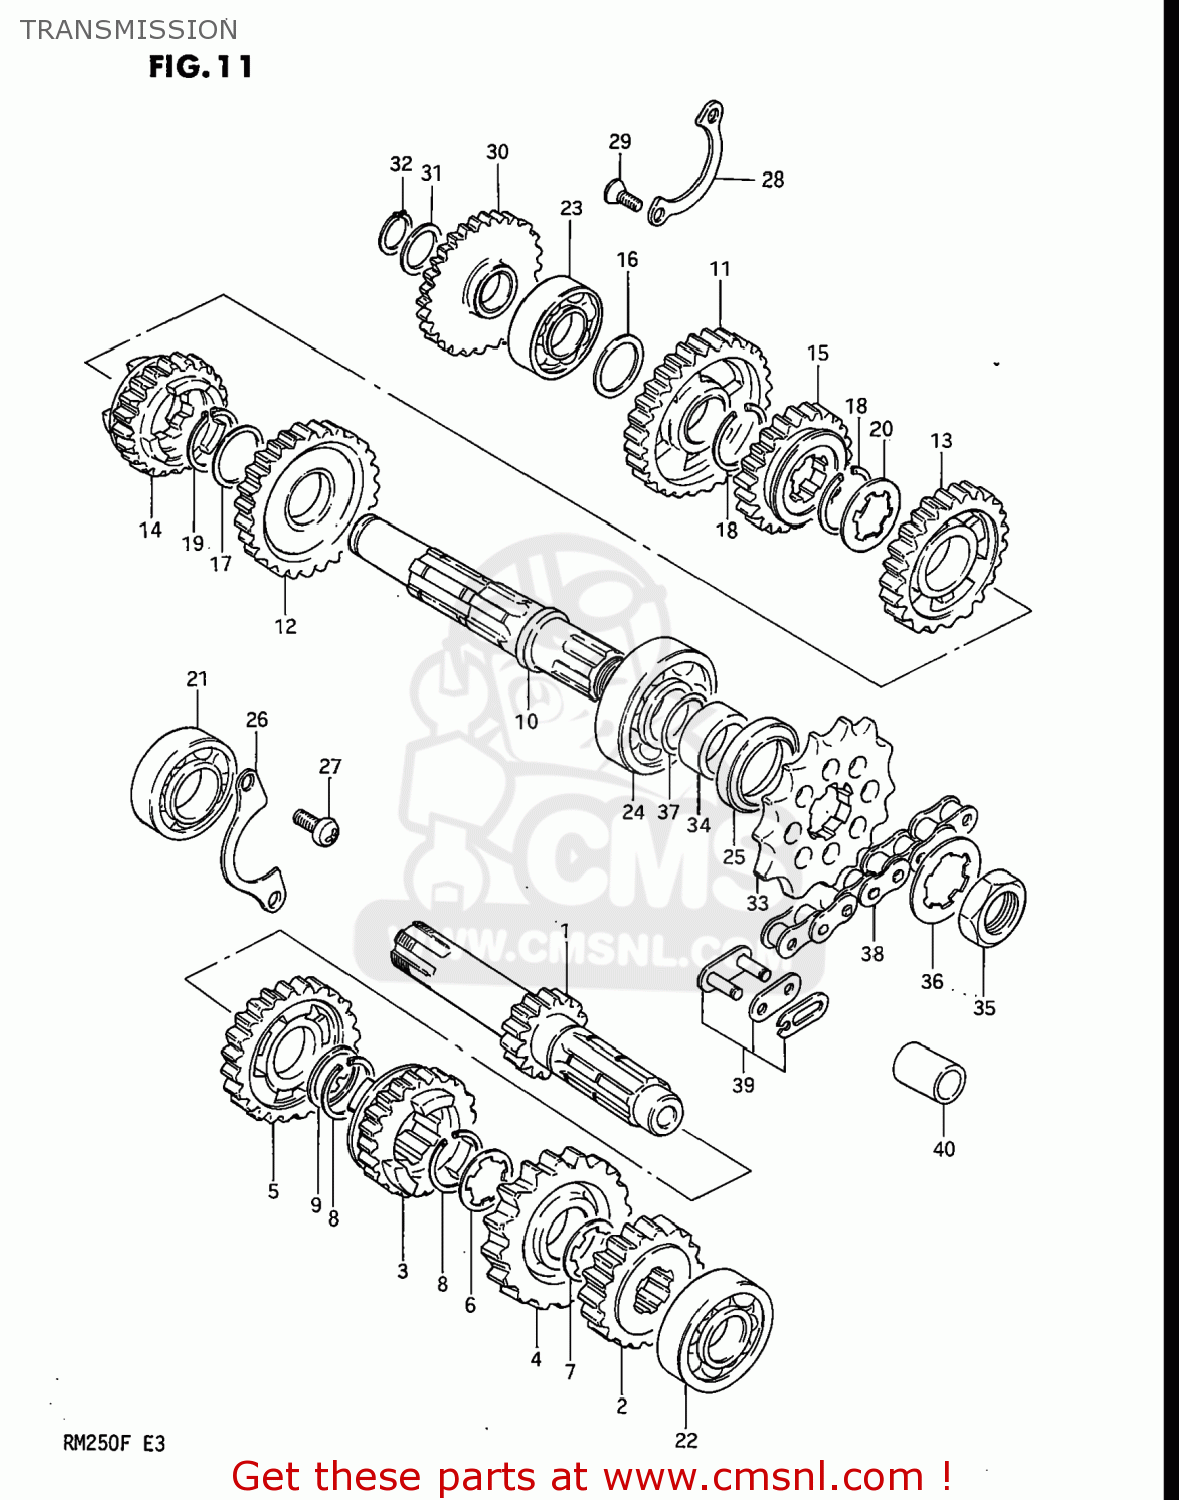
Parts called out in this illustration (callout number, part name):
1	SHAFT,COUNTER
2	GEAR,SECOND DRIVE
3	GEAR,THIRD DRIVE
4	GEAR,FOURTH DRIVE
5	GEAR,FIFTH DRIVE
6	WASHER,LOCK
7	WASHER,LOCK
8	CIRCLIP
9	SHIM(22X28X0.5)
10	SHAFT,DRIVE
11	GEAR,FIRST DRIVEN
12	GEAR,SECOND DRIVEN
13	GEAR,THIRD DRIVEN
14	GEAR,FOURTH DRIVEN
15	GEAR,FIFTH DRIVEN
16	WASHER
17	SHIM
18	CIRCLIP
19	CIRCLIP,25MM
20	WASHER,LOCK
21	BEARING(20X52X15)
22	BEARING(17X40X12)
23	BEARING(17X40X12)
24	BEARING
25	SEAL,OIL(32X42X6)
26	PLATE,COUNTERSHAFT BEARING
27	SCREW 6X12
28	PLATE,DRIVESHAFT BEARING
29	SCREW
30	GEAR,KICK STARTER IDLE
31	WASHER
32	CIRCLIP
33	SPROCKET,ENGINE
34	SPACER(22X32X9.5)
35	NUT
36	WASHER,LOCK
37	O RING(D:1.7,ID:22)
38	CHAIN ASSEMBLY,DRIVE
39	JOINT ASSEMBLY,CHAIN
40	SPACER(12X20X15.3)
